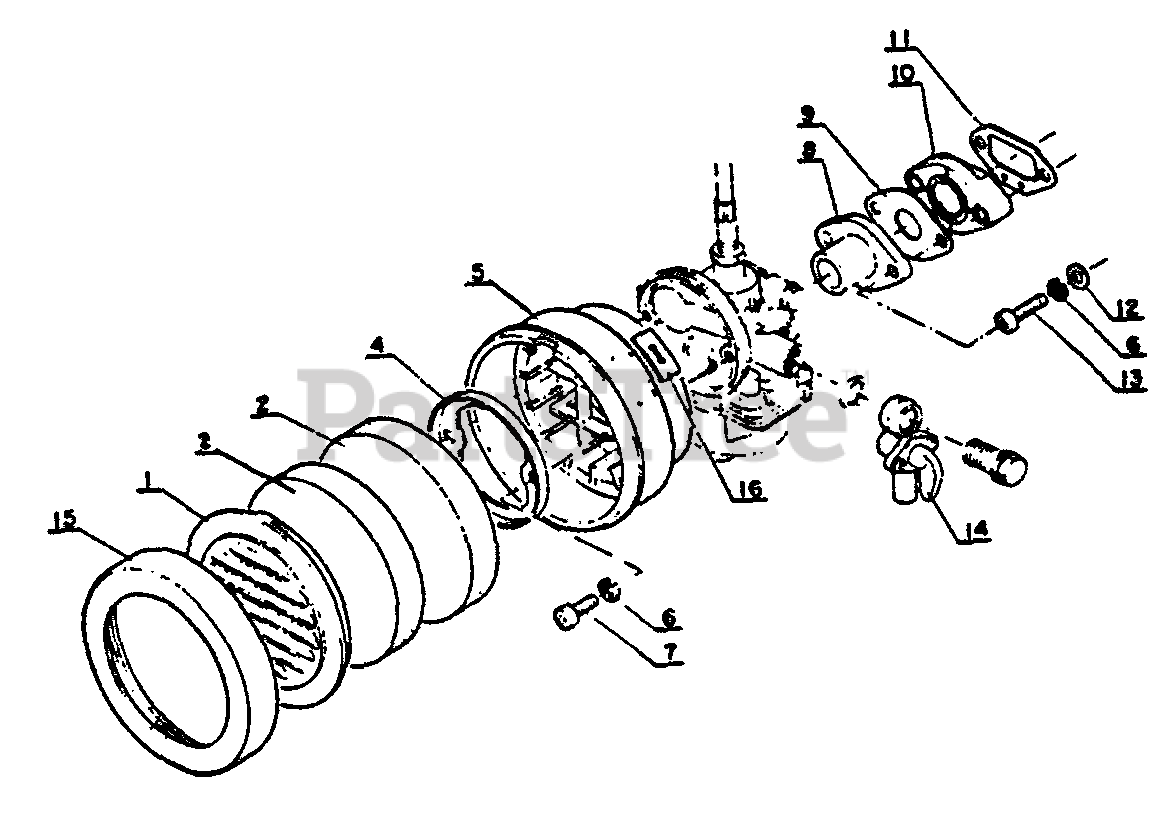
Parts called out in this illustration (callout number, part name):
1	COVER, AIR FILTER
2	FILTER, AIR
4	BRACKET, AIR CLEANER
5	CASE, AIR FILTER
6	LOCKWASHER - 4
7	SCREW - 4X10
8	ADAPTOR, INTAKE
9	GASKET, INTAKE
10	INSULATOR, INTAKE
11	GASKET, INTAKE
12	WASHER - 4
13	SCREW - 4X25
14	FUEL VALVE ASSY
15	COVER, AIR FILTER
16	LABEL - CHOKE
